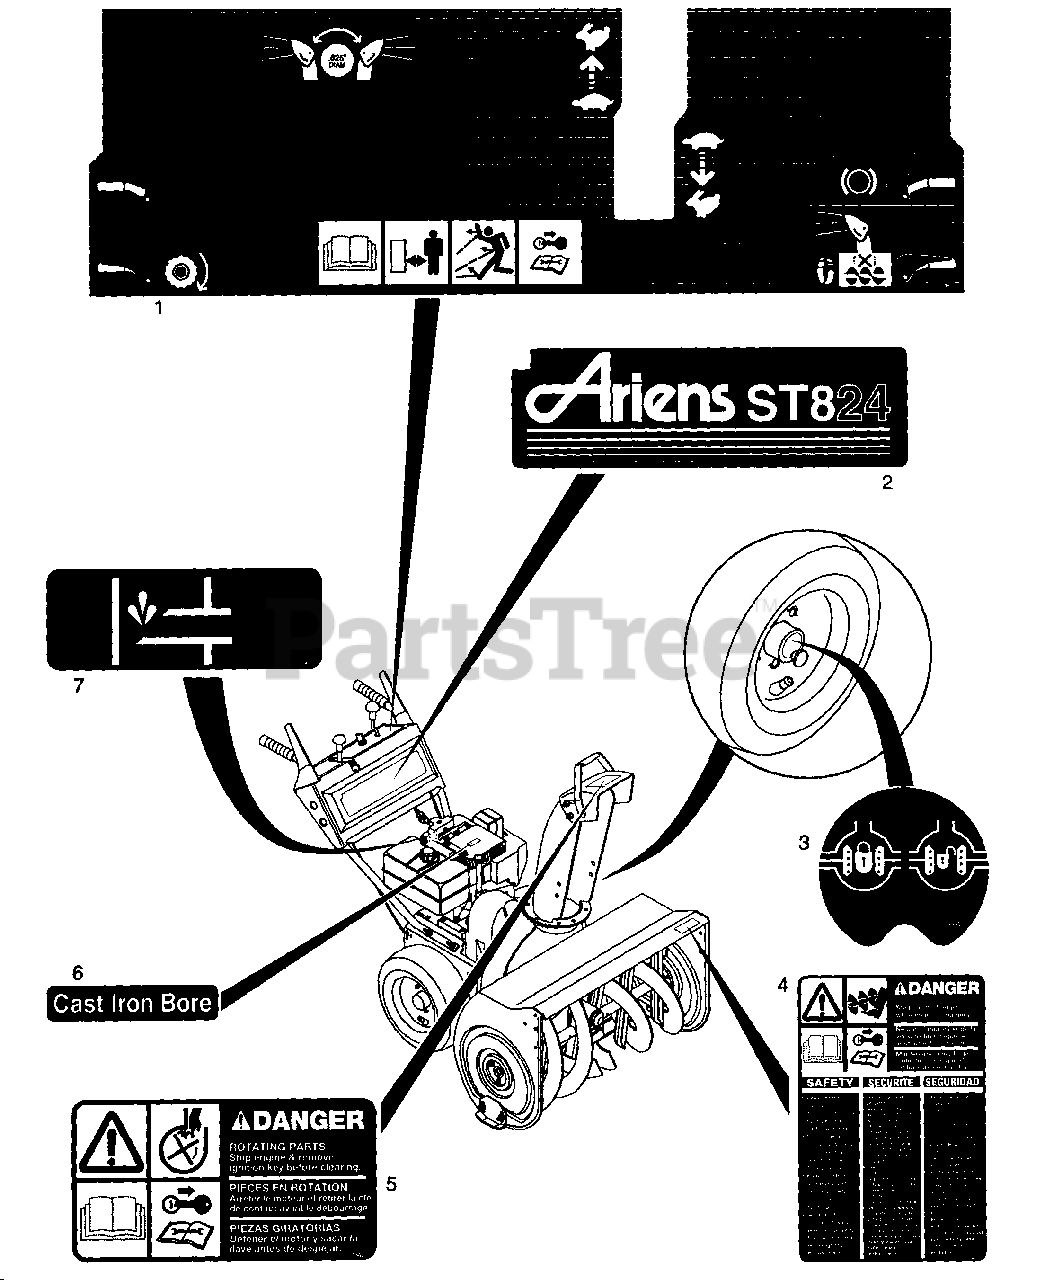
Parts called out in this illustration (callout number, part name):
1	DECAL, DASH
2	DECAL - ST824
3	DIFFERENTIAL LOCK DECAL
4	DECAL, DANGER
5	DECAL, DANGER - ROT. PARTS
6	DECAL - CAST IRON BORE
7	DECAL, PRIMER "TECUMSEH'S"
